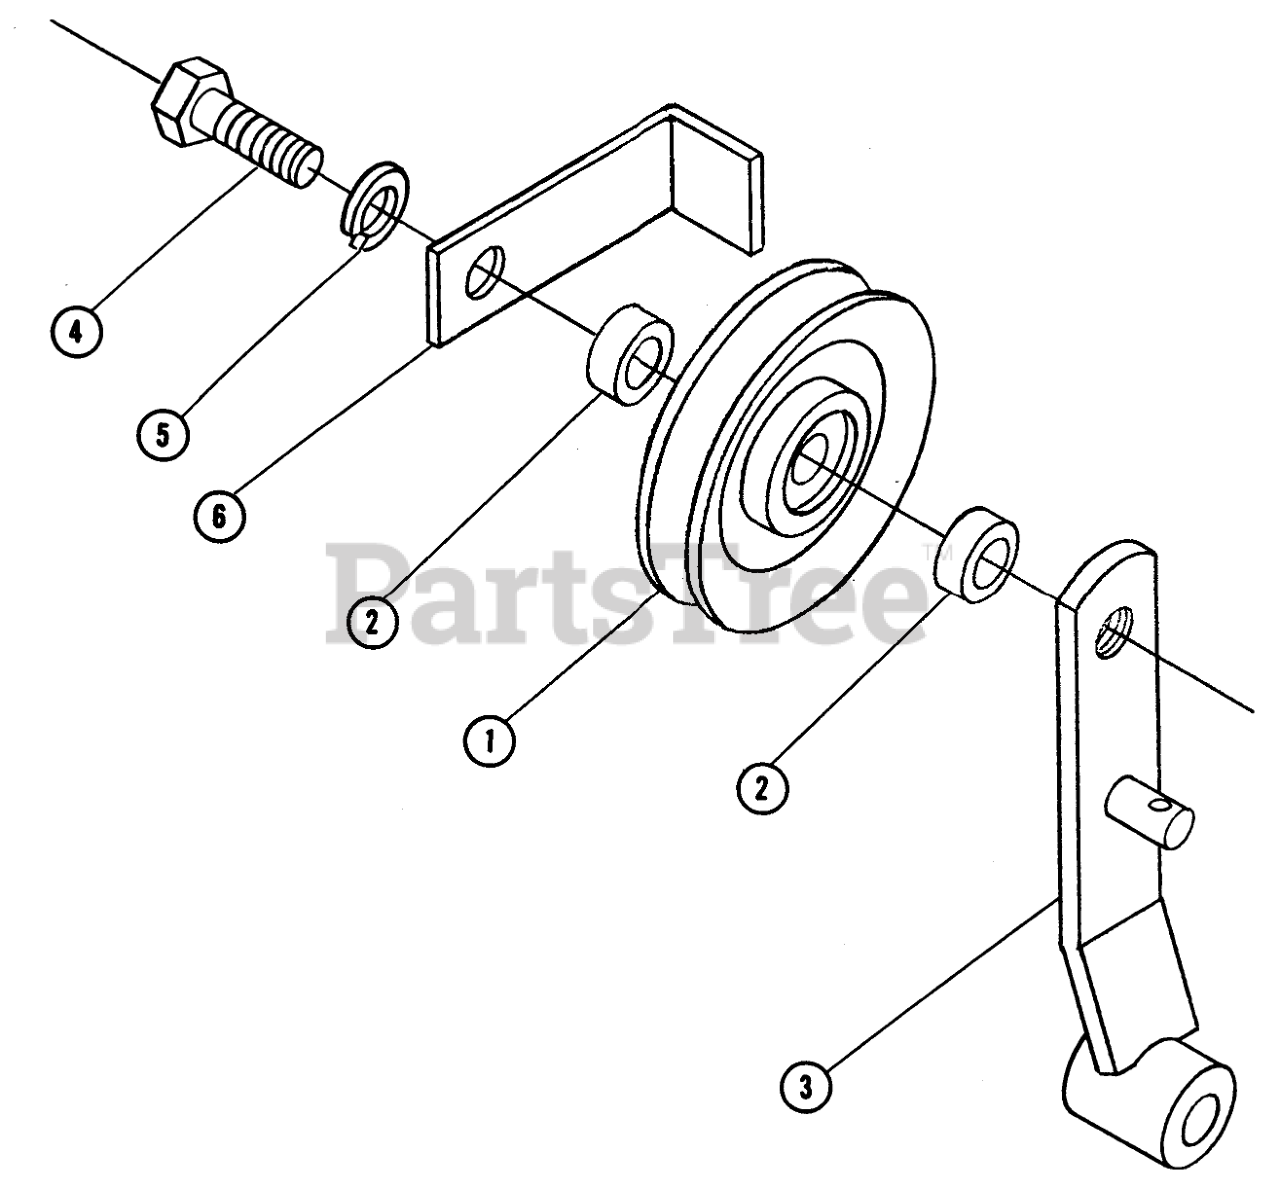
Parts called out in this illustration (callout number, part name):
1	Pulley
2	BUSHING
3	Ass-y. Bracket Idler
4	Bolt 3/8-16 x 1
5	Lockwasher
6	Bracket - Belt Stop
